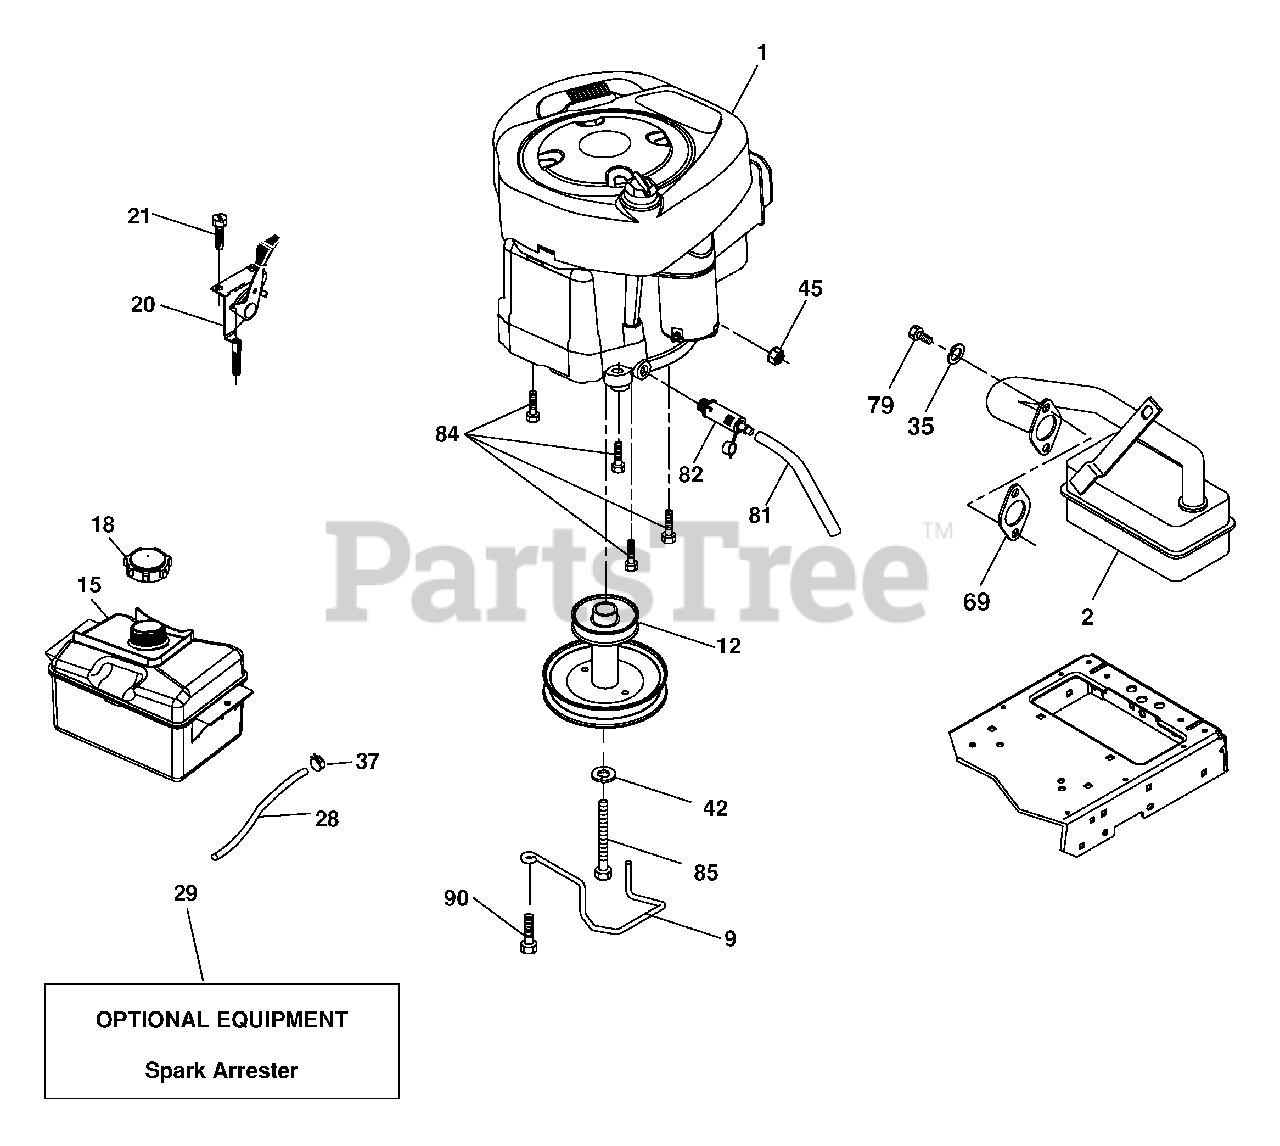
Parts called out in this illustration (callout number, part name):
2	Muffl er
9	Keeper Belt Engine
12	Pulley Engine
15	Tank Fuel 2.5
18	Cap Asm
20	Control Throttle
21	Screw 10 x 3/4 Single Lead-Hex
28	Fuel Line
29	Spark Arrester Kit
35	Washer Split
37	Clamp Hose
42	Washer Lock 7/16
45	Nut Keps Hex 1/4-20 unc
69	Gasket
79	Screw Socket Head 5/16-18 x .75
81	Tube Drain Oil Easy
82	Plug Drain Oil
84	Screw 3/8-16 x 1-1/4
85	Bolt Hex 7/16-20 x 4 x 5 Ga.-1.5
90	Screw 3/8-16 x 1
